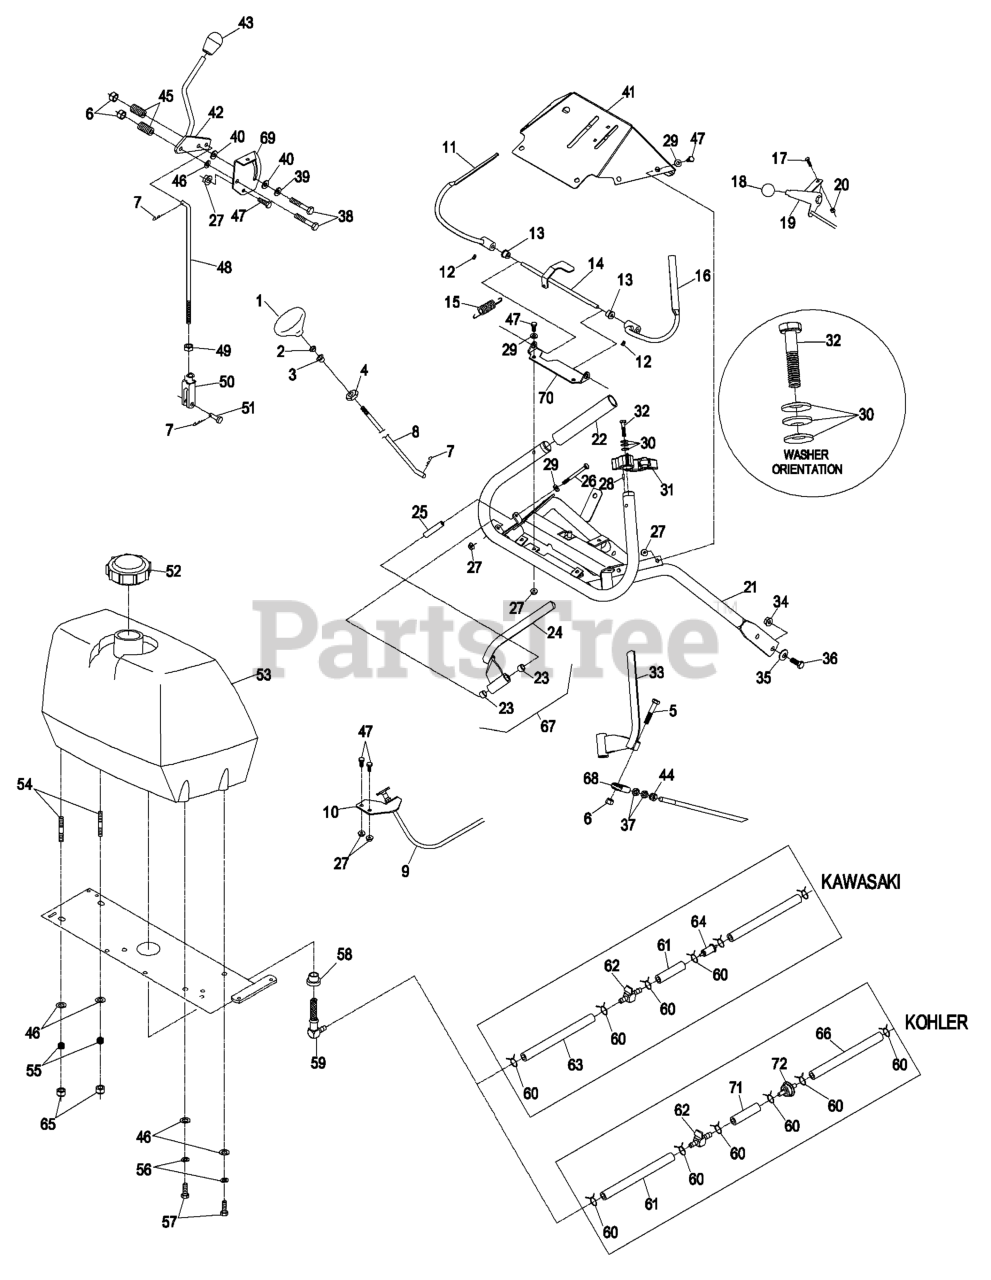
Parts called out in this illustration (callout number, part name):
1	KNOB-PUSH / PULL
2	NUT-JAM
3	BEARING-NYLON
4	NUT-PUSH
5	SCREW-HH
6	NUT-LOCK, NI
7	PIN-COTTER
8	LINKAGE,BLADE PUSH/PULL
9	CABLE-CHOKE
10	BRACKET-CABLE, CHOKE
12	SCREW-SET
13	BUSHING-NYLON
14	WLD,OPC LEVER AXLE
15	SPRING-EXTENSION
17	BOLT-CARR
18	KNOB-BALL
19	CONTROL,THROTTLE
20	NUT-LOCK, NI
21	WLD,VH ECS HANDLE
22	GRIP-BAR, HANDLE
23	BUSHING-SLEEVE
25	BUSHING-LEVER, DRIVE
26	SCREW-HH
27	NUT-HF
29	WASHER-FLAT
30	WASHER-SPRING
31	ASM,LATCH RH THUMB
32	SCREW-HH
34	NUT-HHF, WHIZ
35	WASHER-BELLEVILLE
36	SCREW-HH
37	NUT-HJ
38	SCREW-HH
39	WASHER-FRICTION
40	WASHER-FRICTION
43	KNOB, FE.LCKG. BLACK
44	NUT-HEX
45	SPRING-COMPRESSION
46	WASHER-PLAIN
47	SCREW-HH
48	ROD-CONTROL, SPEED
49	NUT-JAM
50	YOKE-ADJUSTABLE
51	PIN-CLEVIS
52	CAP-FUEL
54	STUD
55	SPRING-TANK, FUEL
56	WASHER-LOCK
57	SCREW-HH
59	ELBOW-TANK, FUEL
61	HOSE-FUEL
62	VALVE-FUEL
63	HOSE-FUEL
64	Kawasaki Pn 41019-1055 Filter W/6" Fuel Line
65	NUT-LOCK, NI
66	HOSE-LINE, FUEL
67	DRIVE LEVER-ASM, RH
68	JOINT-BALL, END
69	BRACKET,SHIFTER SLIDE (PL
70	BRACKET,OPC AXLE
71	HOSE-LINE, FUEL
